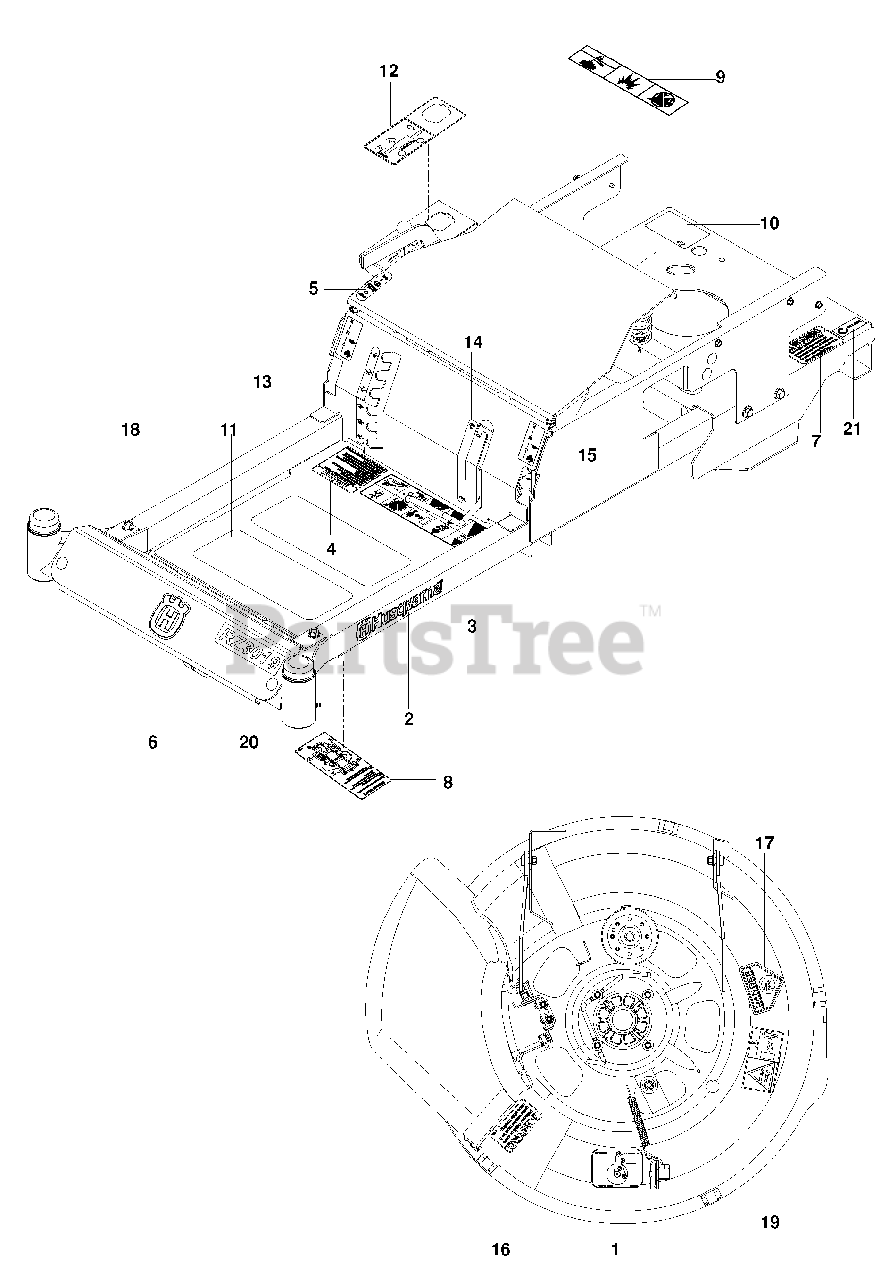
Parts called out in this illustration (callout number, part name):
1	DECAL, BELT ROUTING
2	DECAL, HUSQVARNA
3	DECAL, SAFETY WARNING
4	DECAL, WARNINGS
5	DECAL, PARK BRAKE
6	DECAL, CROWN
7	DECAL, PROP 65
8	DECAL, SERVICE
9	DECAL, BATTERY WARNING
10	DECAL, DO NOT TOW
11	PAD, ABRASIVE
12	DECAL, CONTROL PANEL
13	DECAL, DECK HEIGHT
14	DECAL, BLADE ENGAGE
15	DECAL, MOTION CONTROL
16	DECAL, WARNING
17	DECAL, BLADE WARN
19	DECAL, SEVERING
20	DECAL, RZ3019
21	DECAL, ECM
